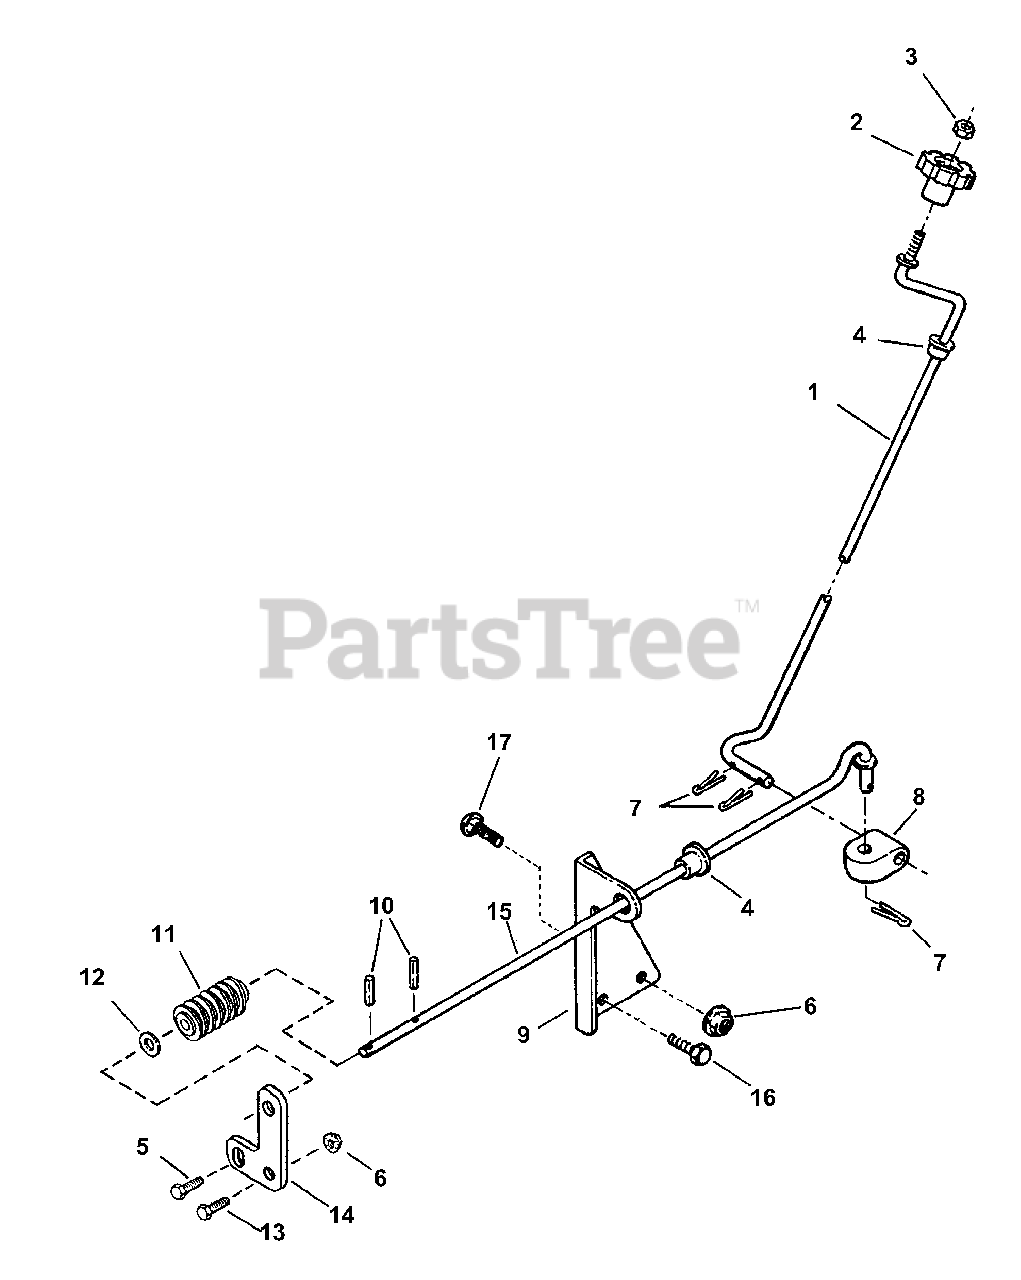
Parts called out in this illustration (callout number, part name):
1	CRANK, Chute
2	KNOB, Chute Crank
3	NUT, 5/16-18 Hex Center Lock, Grade B
4	BUSHING
5	SCREW, 1/4-20 x 1/2" Hex Washer Self-Tapping
6	NUT, 5/16-18 Hex Flange Lock, Grade 5
7	PIN, 3/32 x 3/4" Cotter
9	BRACKET, Shaft
10	PIN, 1/8 x 3/4" Roll
11	WORM
12	WASHER, Spring
13	SCREW, 5/16-18 x 5/8" Hex Head Cap, Grade 5
14	BRACKET, Worm Shaft
15	SHAFT, Worm (long)
16	SCREW, 5/16-18 1/2" Hex Washer Self-Tapping
17	BOLT, 5/16-18 x 5/8" Short Neck Carriage, Grade 5
